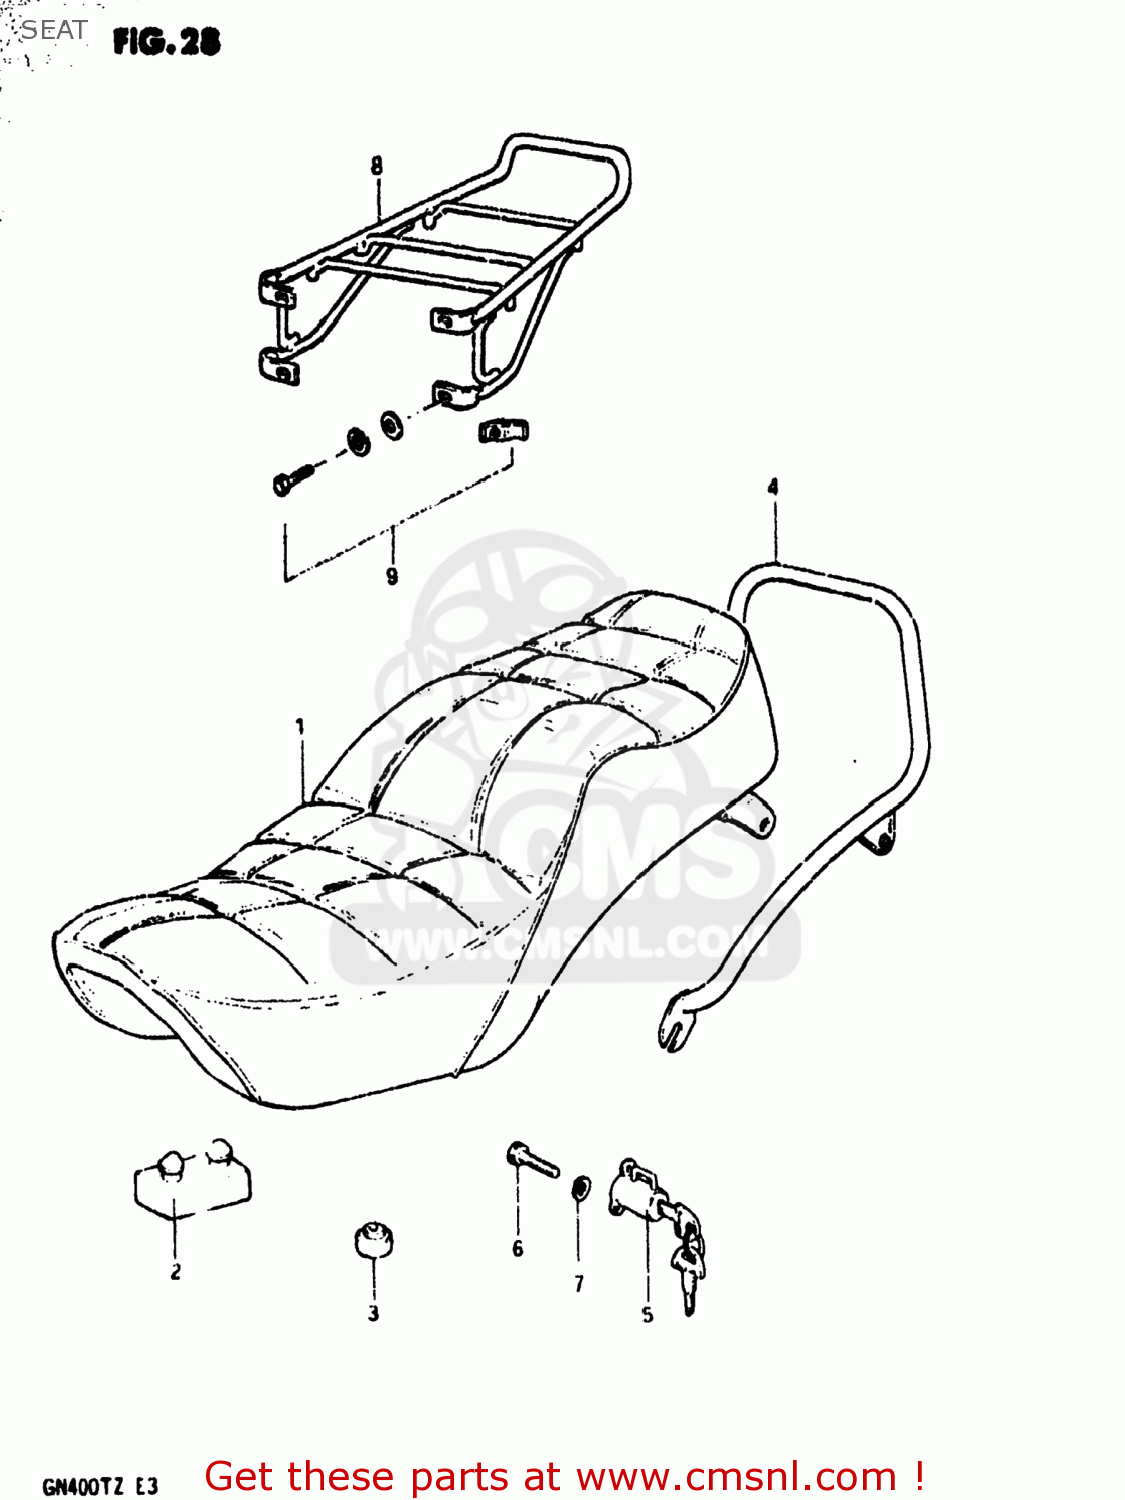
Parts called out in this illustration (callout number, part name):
1	SEAT ASSEMBLY
2	CUSHION
3	CUSHION
4	HANDLE,PILLION RIDER
5	LOCK ASSEMBLY,HELMET
6	BOLT 6X11
7	LOCK WASHER
8	CARRIER
9	FITTING SET,CARRIER
